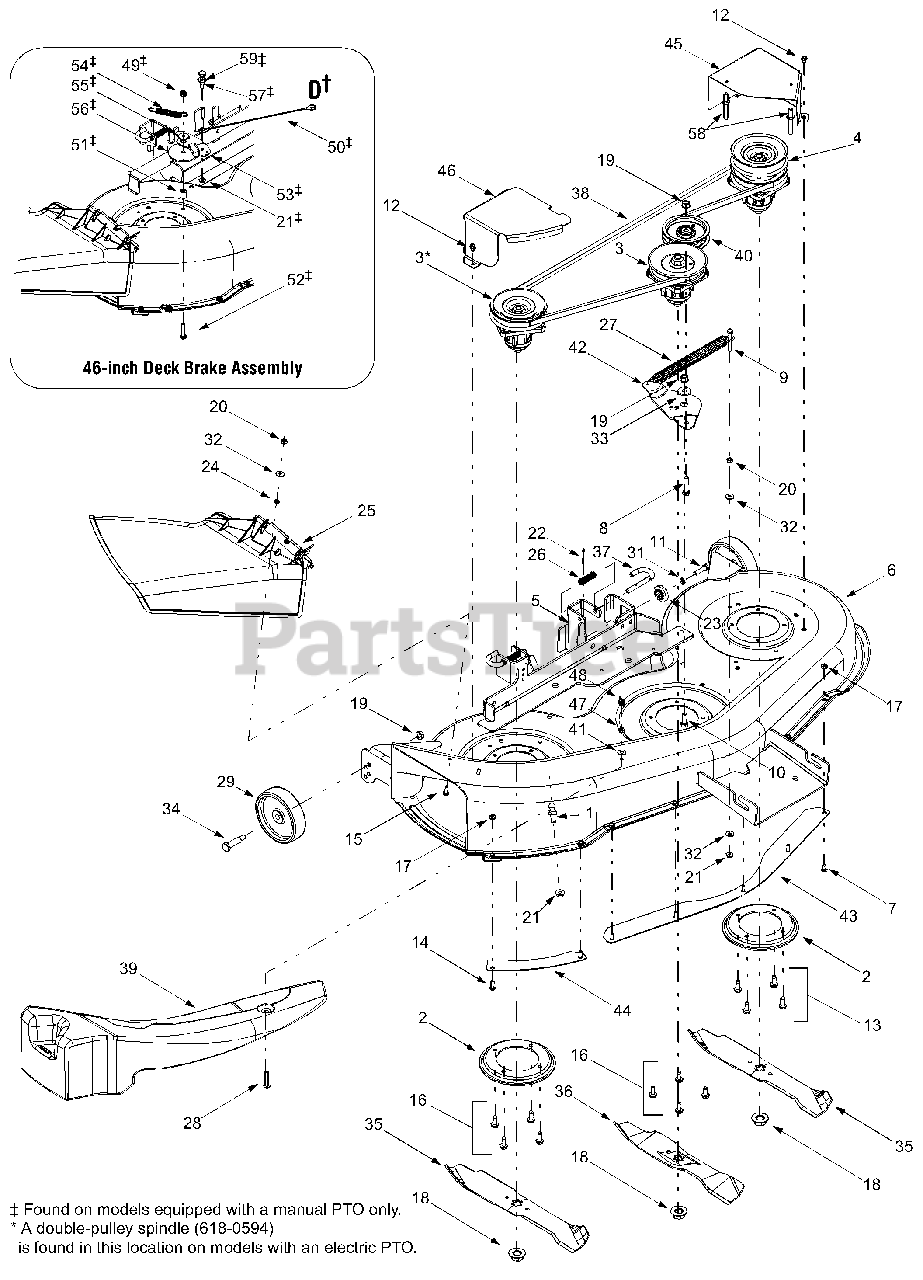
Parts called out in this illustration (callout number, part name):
1	Grass Catcher Pin
4	Double Pulley Spindle Assembly
7	Carriage Screw, 1/4-20 x.50
8	Hex Cap Screw, 3/8-16 x 1.5
9	Hex Cap Screw, 1/4-20 x 2.0
10	Hex Cap Screw, 3/8-16 x 1.0
11	Hex Cap Screw, 5/8-18 x 1.25
12	Self-tapping Screw,1/4-20 x.5
13	Self-tapping Screw,15/16-18 x.875
14	Hex Screw, 1/4-20 x.75
15	Hex Cap Screw, 1/4-20 x.62
16	Self-tapping Screw, 5/16-18 x.75
17	Hex Sems Nut, 1/4-20
18	Hex Flange Nut, 5/8-18
19	Flange Lock Nut, 3/8-16
20	Hex Nut, 1/4-20
21	Hex Flange Lock Nut, 1/4-20
22	Cotter Pin, 1/8 x 1.25
23	Deck Adjustment Gear
24	Push Nut.25 x.5
25	Side Discharge Chute Assembly
26	Compression Spring,.406 x.531 x 1.75
27	Extension Spring,.91 x 7.3
28	Screw, 1/4-20 x 1.5
29	Deck Wheel, 5 x 1.38
31	Lock Washer, 5/16
32	Bell Washer,.265 x.75 x.062
33	Shoulder Spacer,.625 x 1.16
34	Shoulder Screw
35	Three-in-one Blade, Star Center, 16.28"
36	Three-in-one Blade, Star Center, 14.88"
37	Deck Release Pin
38	Deck Belt, Poly
39	Mulch Plug
40	Idler Pulley, 3.5
41	Flat Washer,.28 x.74 x.063
47	Hex Nut, 1/4-20
48	Wing Nut, 1/4-20
49	Hex Nut, 5/16-18
50	Bracket Cable, 12"
51	Spacer,.385 x.625 x.70
52	Hex Cap Screw, 5/16-18 x 1.5
53	Deck Brake Assembly
54	Extension Spring,.5 x 3.97
55	Shoulder Spacer
56	Flat Washer,.34 x 2.25 x.1
57	Pin, 1/4-20
58	Belt Guard Pin
59	Flat Washer,.385 x.62 x.06
